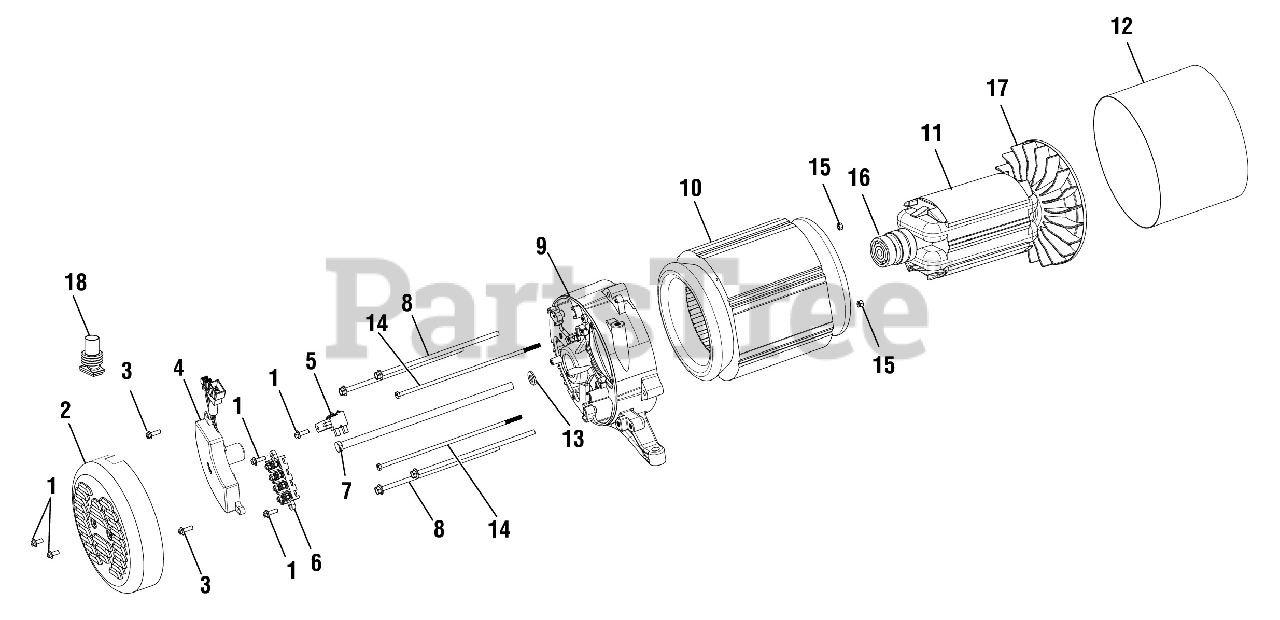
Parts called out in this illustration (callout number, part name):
1	Bolt (M5 x 16 mm, Hex Flange Hd.)
2	Brush Cover
3	Bolt (M5 x 12 mm, Hex Flange Hd.)
4	Automatic Voltage Regulator (5000 Watt)
5	Brush Assembly 190 mm
6	Terminal Block
7	Bolt (M10 x 280 mm)
8	Stator Bolt (M6 x 198 mm)
9	Bearing Support
10	Stator Assembly
11	Rotor Assembly
13	Washer (ID10.5 x OD25 x 2t)
14	Bolt (M5, Hex Hd.)
15	Hex Nut (M5)
16	Ball Bearing (190 mm)
17	Fan (190 mm)
18	Rubber Sleeve
